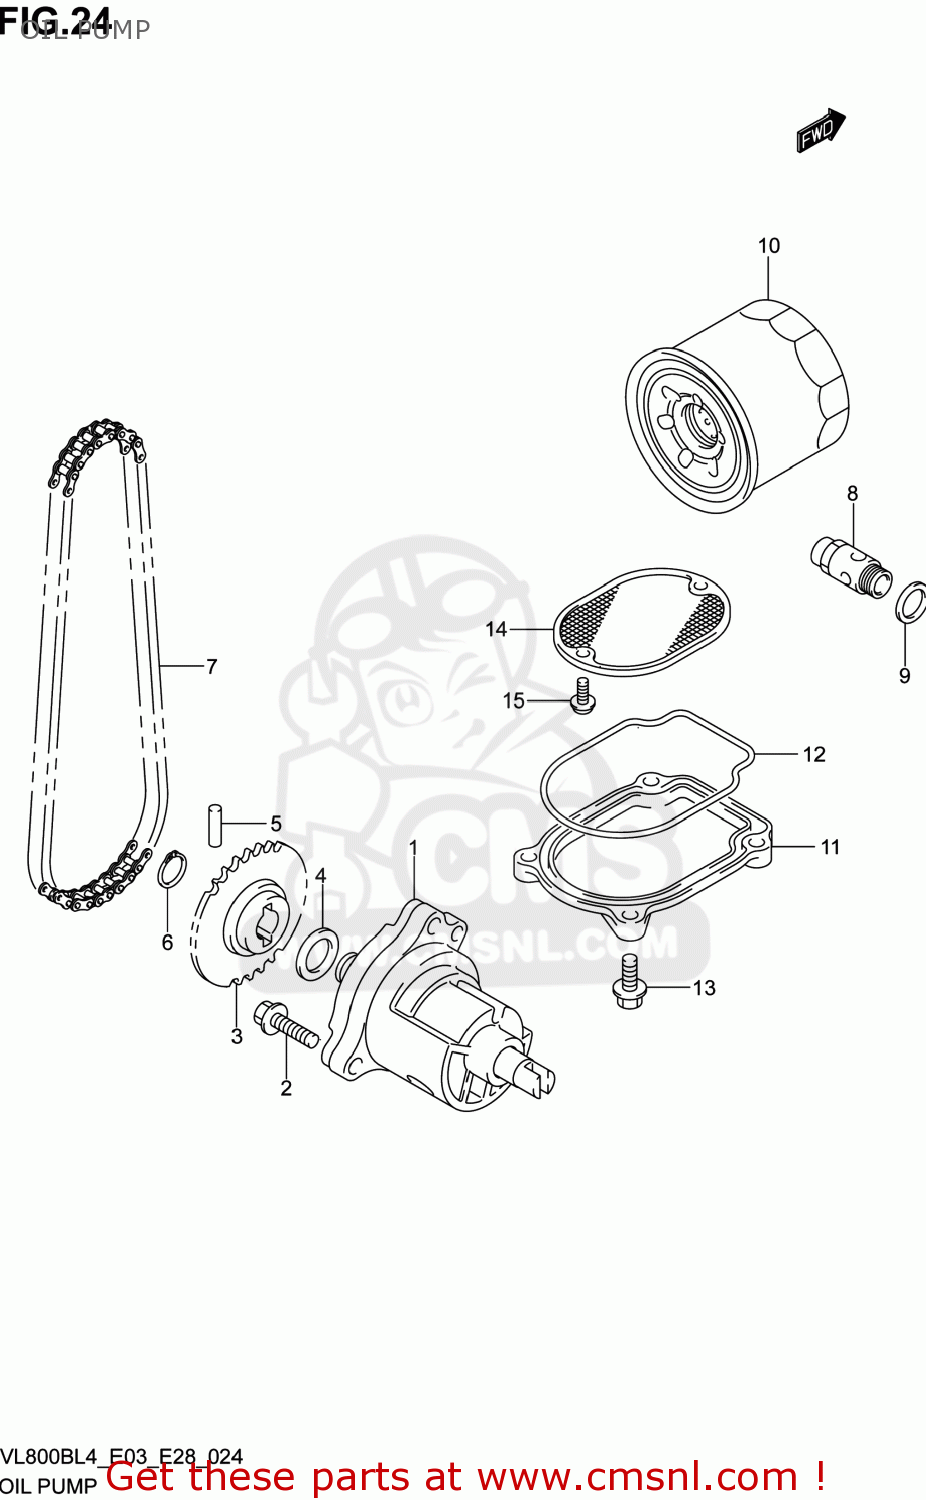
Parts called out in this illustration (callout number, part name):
1	PUMP ASSY,ENGINE OIL
2	BOLT
3	SPROCKET,OIL PUMP DRIVEN
4	SHIM(12X20X0.5)
5	PIN(5X18)
6	CIRCLIP
7	CHAIN,OIL PUMP DRIVE
8	VALVE ASSY,OIL RELIEF
9	GASKET(16X22X2) (NAS)
10	FILTER ASSY,ENGINE OIL
11	CAP,OIL STRAINER
12	O RING,OIL STRAINER CAP
13	BOLT
14	STRAINER,ENGINE OIL
15	SCREW
